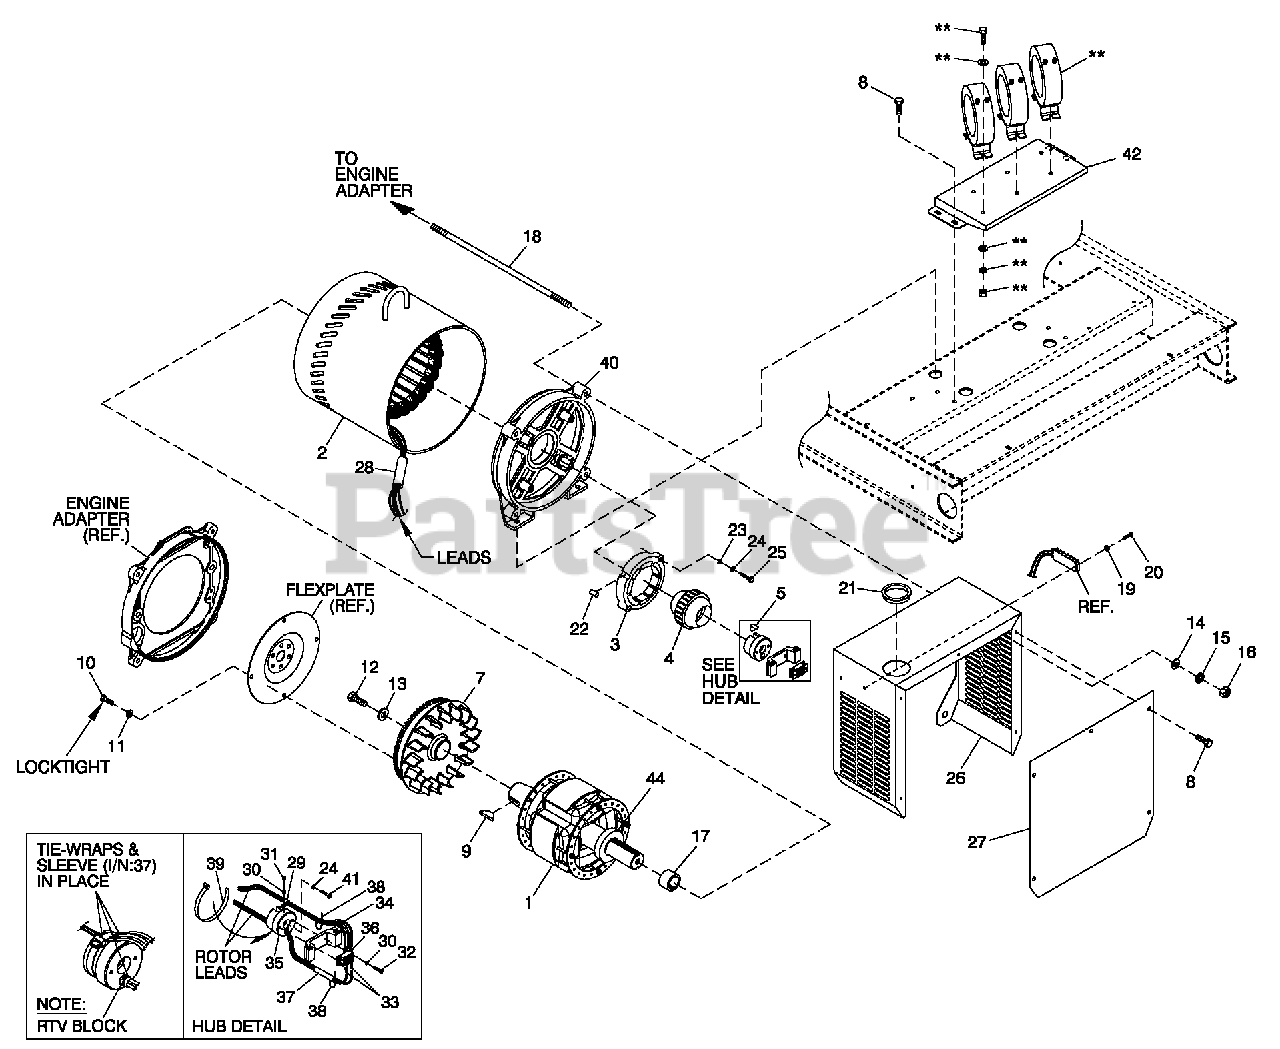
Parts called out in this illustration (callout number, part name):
1	ROTOR 390 70AB3 CPL
2	STATOR 390 70AB3 CPL
3	EXITER FIELD 2"LG SPD CONN
4	ASSY EXCITER 2 . 00" STK
5	KEY SQ 3/8 X 3-1/4 STEEL
7	ASSY FLYWHEEL CPL
8	SCREW THF M6-1 X 16 N WA Z/JS
9	KEY WOODRUFF #E
10	SCREW HHC M10-1.50 X 16 G10 .9
11	WASHER LOCK M10
12	SCREW HHC M16-2 . 0X45G8 .8
13	SPACER.69 X 2.75 X .37 ST/ZNC
14	WASHER FLAT M14
15	WASHER LOCK M14
16	NUT HEX M14-2.0G8YEL CHR
17	COLLAR SLIP FIT 390 MM
18	STUD M14-2.0X650 G5 ZINC
19	WASHER LOCK #6
20	SCREW PHTT #6-32 X 1/2 ZYC
21	BUSHING SNAP SB-2 .5-31
22	PIN DOWEL 1/2 X 1-1/4
23	WASHER FLAT M12
24	WASHER LOCK M12
25	SCREW HHC M12-1.75 X 80 G10 .9
26	SHIELD ALT EXCITER 390
27	COVER EXCITER SHIELD
28	SLEEVE RUBBER
29	CLAMP VINYL .312 X .203 Z
30	WASHER SHAKEPROOFINT #8
31	SCREW HHM #8-32X3/8
32	SCREW HHM #8-32X7/8
33	LUGRT-ANG #10/10-12
34	BRIDGE SUPPORT DIODE 15"
35	CAP END ROTOR 390MM
36	ASSY BRIDGE RECTIFIER
37	SLEEVING UL #0.330 ID (3" LG)
38	TIE WRAP UL 3. 9"X.10" BLK
39	TIE WRAP UL 17.7X. 35 BLK HT
40	REAR BEARING CARRIER CPL
41	SCREW HHC M12-1.75 X 60 G10 .9
42	MOUNT CT'S 5 .4L&6 .8L
43	BUSHING SNAP SB-2 .5-31
44	BEARING BALL 6212 SEALED
